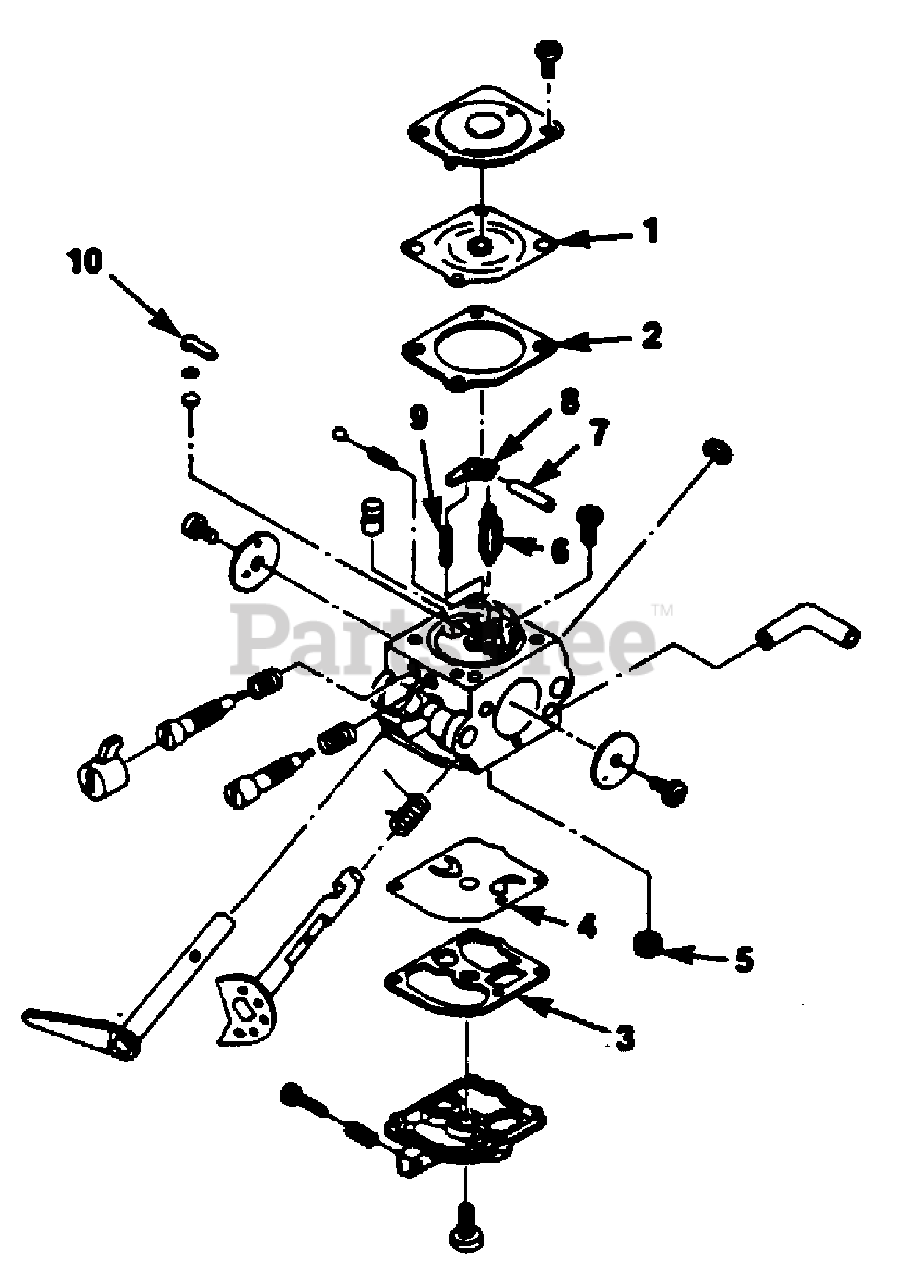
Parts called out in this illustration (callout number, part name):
1	Part of Repair Kit (includes 1-10)
2	Part of Repair Kit (includes 1-10)
3	Part of Repair Kit (includes 1-10)
4	Part of Repair Kit (includes 1-10)
5	Part of Repair Kit (includes 1-10)
6	Part of Repair Kit (includes 1-10)
7	Part of Repair Kit (includes 1-10)
8	Part of Repair Kit (includes 1-10)
9	Part of Repair Kit (includes 1-10)
10	Part of Repair Kit (includes 1-10)
